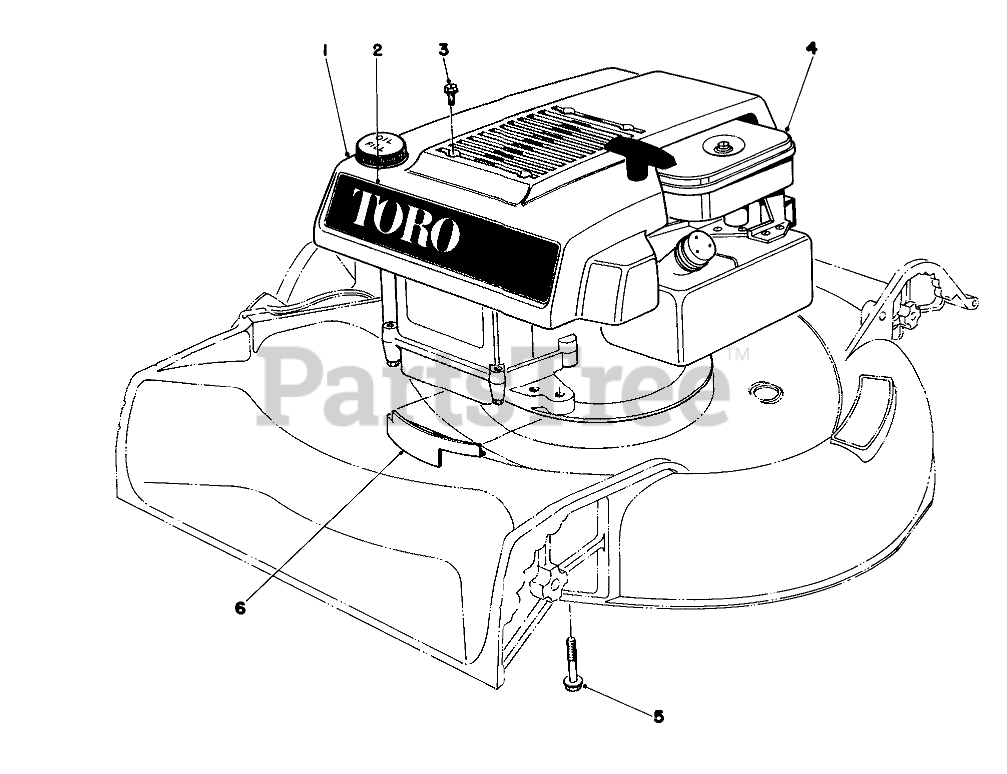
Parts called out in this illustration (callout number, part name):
1	Shroud
2	Decal-Toro
3	8X1/2 SELF TAP SCREW
4	Engine
5	3/8-16 X 2-3/4 CAPSCR
6	HOUSING CAP
